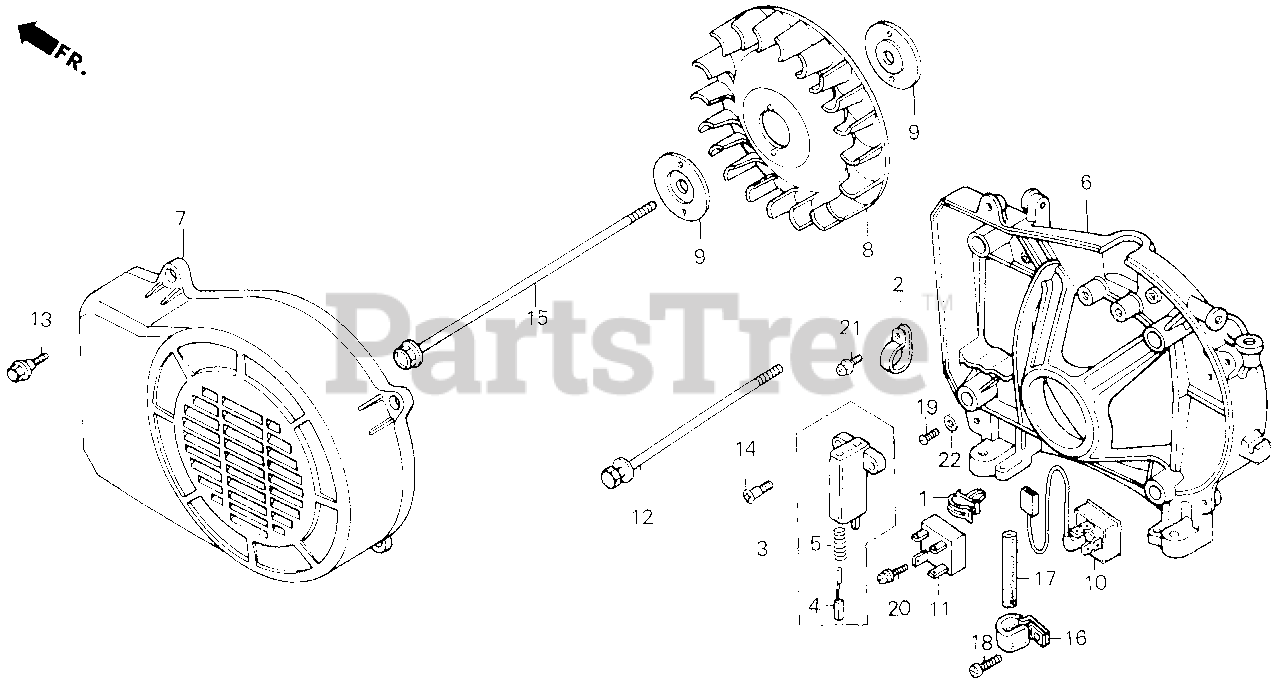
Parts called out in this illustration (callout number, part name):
1	CLAMP, D.C. CABLE
2	CLAMP C, CABLE
3	HOLDER ASSY., BRUSH
5	SPRING, BRUSH
6	HOUSING, RR.
7	COVER, ALTERNATOR END
8	FAN, COOLING
9	PLATE, FAN
10	DIODE, D.C.
11	DIODE, D.C.
12	BOLT, FLANGE (6X137)
13	BOLT, GENERATOR END COVER
14	BOLT, STATOR COVER SETTING
15	BOLT, FLANGE (8X175)
16	CLIP, WIRE
17	TUBE, WIRE
18	SCREW, PAN (5X8)
19	SCREW, PAN (5X12)
20	SCREW-WASHER (4X18)
21	SCREW-WASHER (5X12)
22	WASHER, SPRING (5MM)
